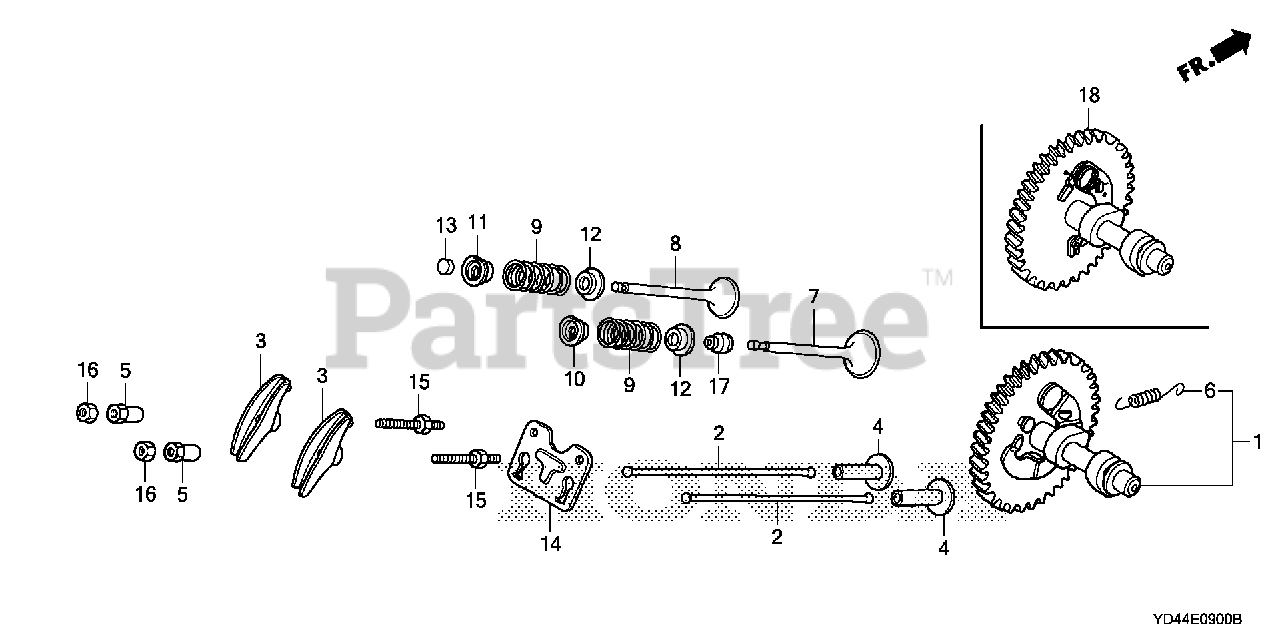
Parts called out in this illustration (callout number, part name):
1	CAMSHAFT ASSY.
2	ROD, PUSH
3	ARM, VALVE ROCKER
4	LIFTER, VALVE
5	PIVOT, ROCKER ARM
6	SPRING, WEIGHT RETURN
7	VALVE, IN.
8	VALVE, EX.
9	SPRING, VALVE
10	RETAINER, IN. VALVE SPRING (EXHAUST SIDE)
11	RETAINER, EX. VALVE SPRING
12	SEAT, VALVE SPRING
13	ROTATOR, VALVE
14	PLATE, PUSH ROD GUIDE
15	BOLT, PIVOT (8MM)
16	NUT, PIVOT ADJ.
17	SEAL, VALVE STEM
